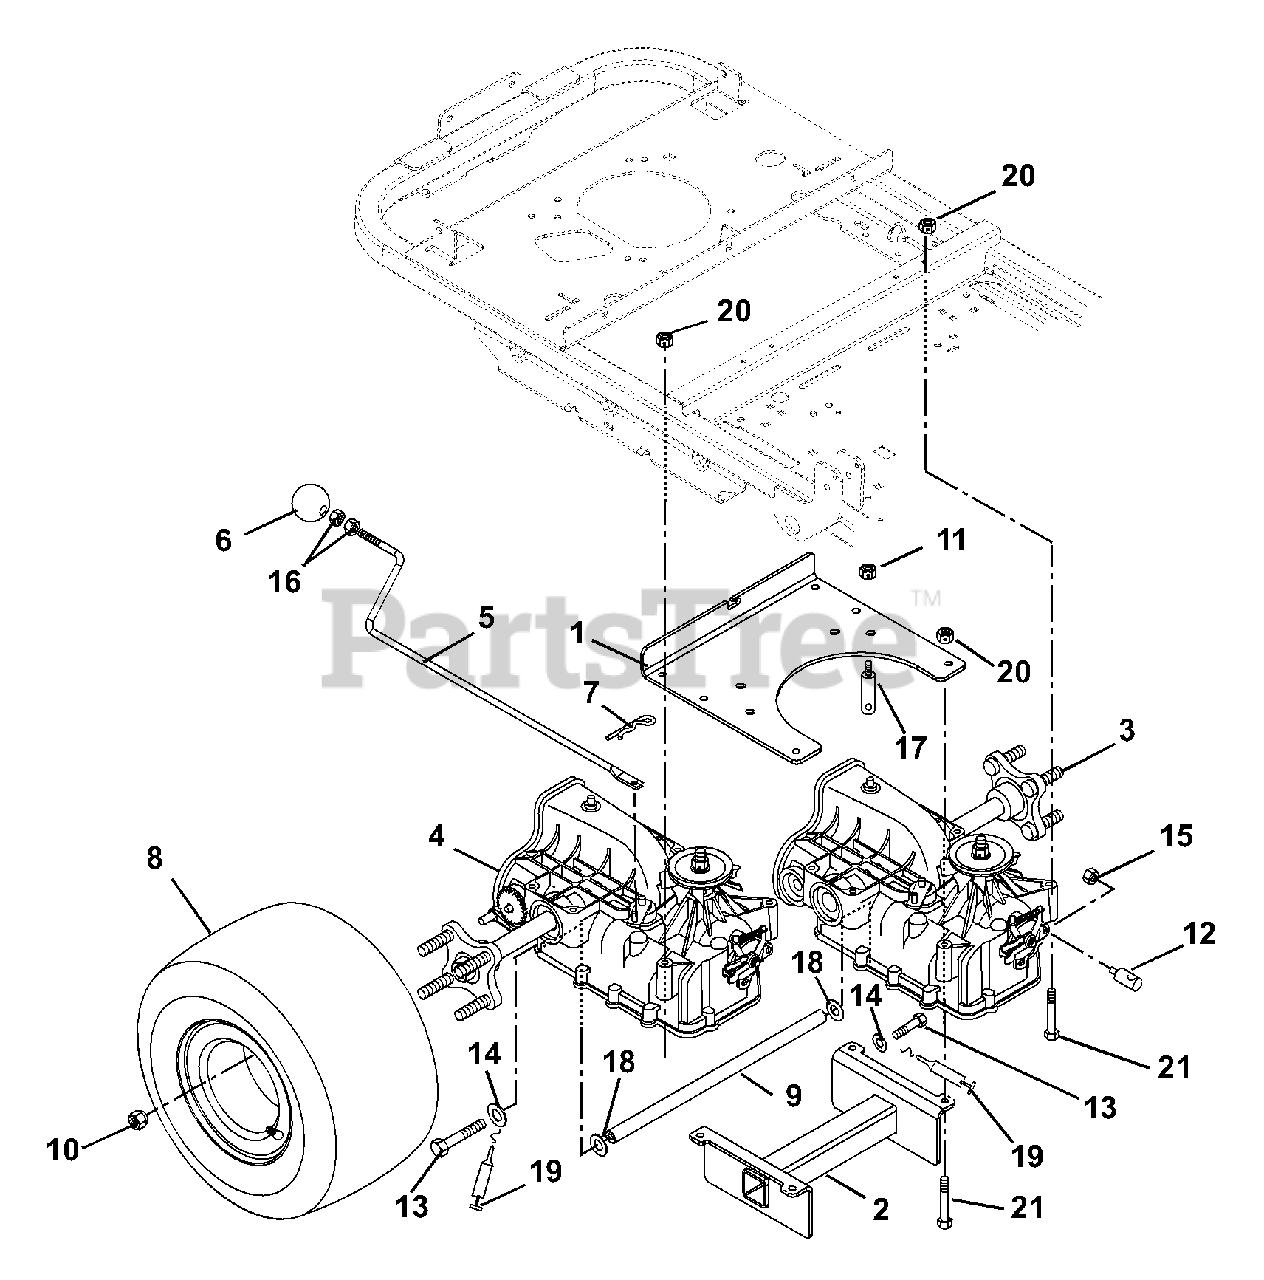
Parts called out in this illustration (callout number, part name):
1	BKT-TRANS AXLE SUPPORT
2	WLDMT-TRANS AXLE BRACE
3	IZT-LH (BIDIRECTIONAL RTN)
3	KIT, LH-BRAKE ARM IZT
4	IZT-RH (BIDIRECTIONAL RTN)
4	KIT,RH-BRAKE ARM IZT
5	ROD-DUMP IZT
6	KNOB, BALL 5/16-18 X 1.5
7	PIN-HAIR INT .08X.18X1.18 YWZC
8	ASSY-TIRE 9.5X18-2PLY
8	ASSY-TIRE 8.5X18 2PLY
9	ROD-AXLE BRACE
10	NUT-LUG .50-20 YWZC
11	@NUT-LK-NYL-FLG .38-16 YWZC
12	ROD PIVOT YWZC
13	@BLT-HEX .31-18X2.50 GR5 YWZC
14	@WSHR-LK .31X.078 REG YWZC
15	@NUT-LK-NYL-FLG .31-18 YWZC
16	NUT- JAM .312-18 YWZC
17	SHOULDER STUD
18	WSHR-FL-STL .328X.87X.179 YWZC
19	ADHSV SEALANT (BLUE) 250 ML
20	@NUT-LK-NYL-FLG .31-18 YWZC
21	@BLT-HEX .31-18X2.75 GR5 YWZC
